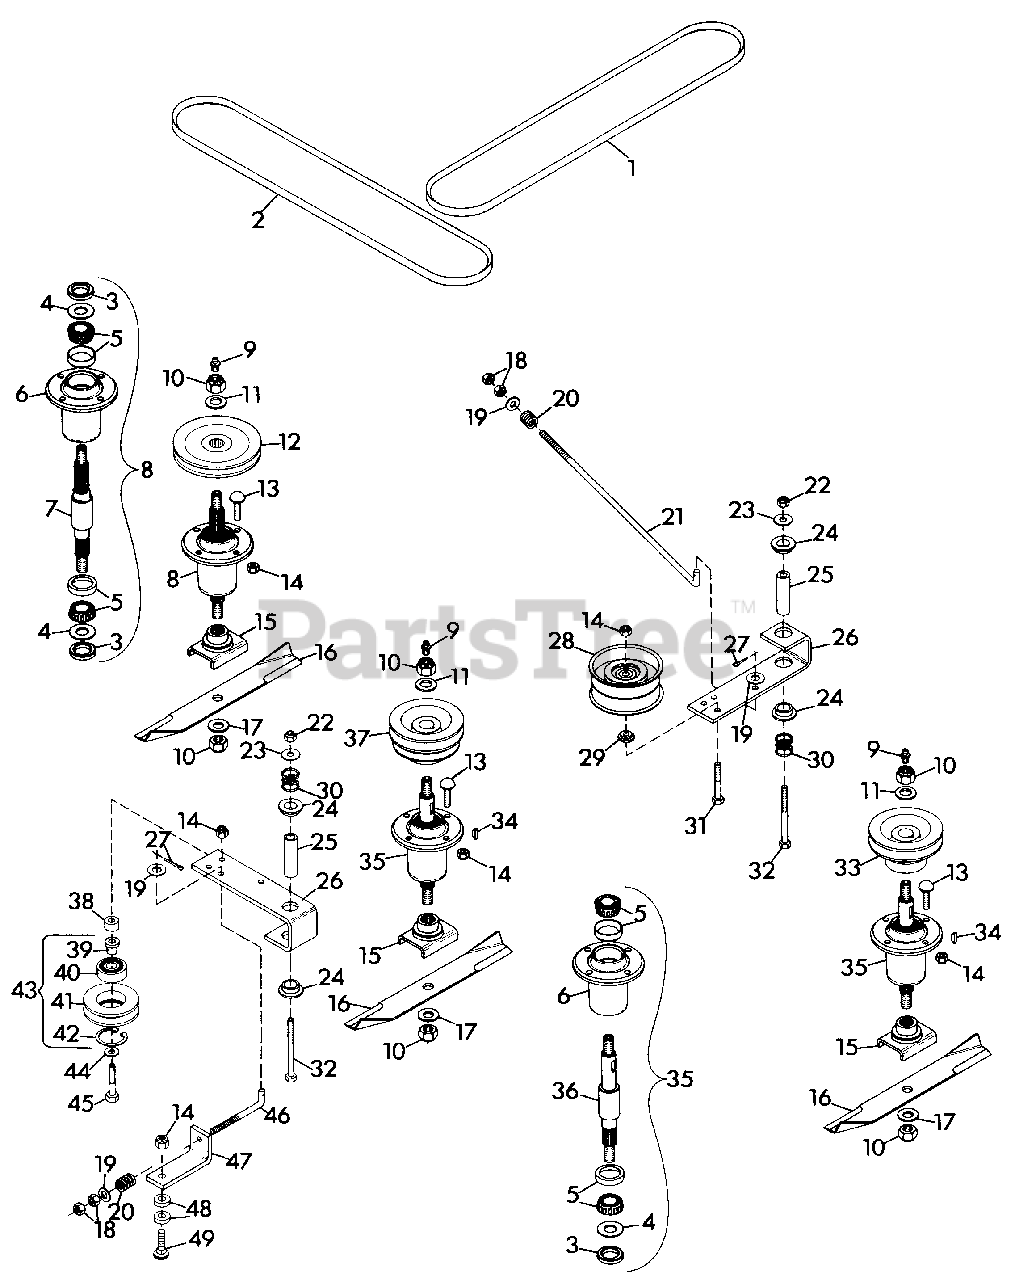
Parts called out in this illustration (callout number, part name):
1	BELT, VEE
2	BELT, VEE
3	SEAL, STEEL(IN 34605)
3	SEAL, STEEL(IN 21306)
4	WASHER, FLAT .975X1.970X.030(IN 34605)
4	WASHER, FLAT .975X1.970X.030(IN 21306)
5	ASSEMBLY, BEARING
6	HOUSING, BEARING
7	SHAFT, SPINDLE
8	ASSEMBLY, SPINDLE
9	FITTING, LUBE 1/8
10	NUT, LOCK 5/8-11
11	WASHER, FLAT .687X1.312X.122
12	PULLEY
13	BOLT, 3/8-16X1.375 RD HD SQ NK
14	NUT, LOCK 3/8-16
15	WELDMENT, BLADE CRADLE
16	BLADE
17	WASHER, FLAT .656X1.312X.095
18	NUT, HEX 3/8-24
19	WASHER, FLAT .406X.812X.065
20	SPRING, COMP. 1X.78
21	ROD, IDLER
22	NUT, LOCK 1/2-13
23	WASHER, FLAT .531X1.250X.100
24	BUSHING, NYLON .76X1X.6 FLG.
25	SPACER
26	ARM, IDLER PIVOT
27	PIN, COTTER .09X.75
28	PULLEY, IDLER
29	BUSHING
30	SPRING, COMP. 1X.80X36 LB/N
31	BOLT, HEX 3/8-16X2.25
32	BOLT, HEX 1/2-13X3.25
33	SHEAVE, SPINDLE
34	KEY, WOODRUFF .250X1 HARD
35	ASSEMBLY, SPINDLE
36	SHAFT, SPINDLE
37	SHEAVE, SPINDLE
38	SPACER, IDLER .406X.625X.48
39	BUSHING, IDLER SHEAVE
40	BEARING, BALL
41	SHEAVE, IDLER
42	RING, RETAINING
43	ASSEMBLY, IDLER SHEAVE
44	WASHER, FLAT .375X1.125X.065
45	BOLT, HEX 3/8-16X2.00
46	ROD, IDLER
47	BRACKET, BELT TENSIONER
48	SPACER
49	BOLT, 3/8-16X1.75 RD HD SQ NK
